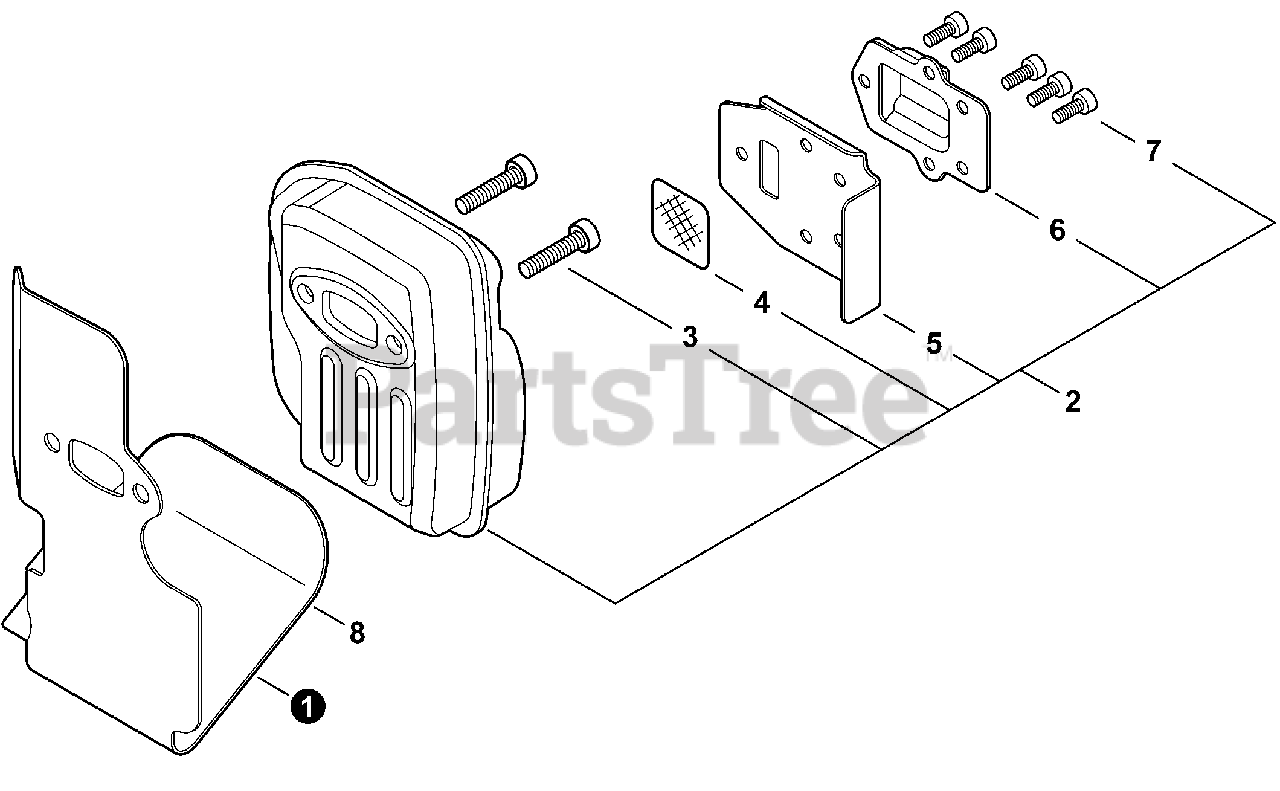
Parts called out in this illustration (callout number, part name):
1	HEAT SHIELD, EXHAUST
2	MUFFLER ASSY
3	BOLT, TORX 5×16
4	SCREEN, SPARK ARRESTER
5	GASKET, EXHAUST
6	GUIDE, EXHAUST
7	BOLT, TORX 4×8
8	GASKET KIT
